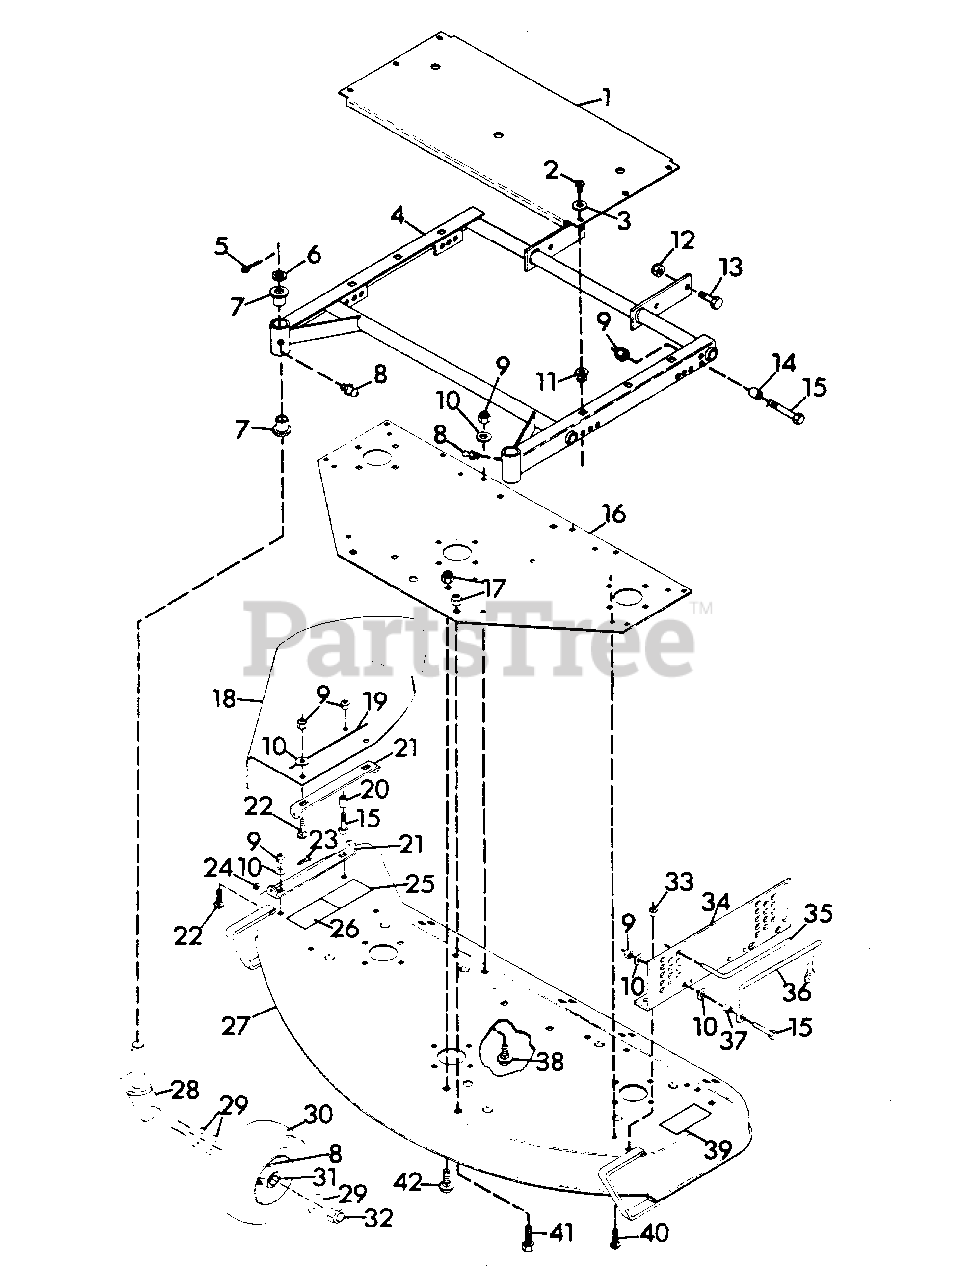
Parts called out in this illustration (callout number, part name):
1	Guard, 50" Mower Belt
2	Screw, Tapping 1/4-20x.625 P/Hd
3	Washer, Flat .281x.625x.065
4	Weldment, Mower Frame
5	Pin, Cotter .187x1.50
6	Race, Bearing Thrust
7	Bushing, Pivot
8	Fitting, Lube 1/4-28
9	Nut, Lock 3/8-16
10	Washer, Flat .406x.812x.065
11	Grommet, Plastic
12	Nut, Lock 5/8-11
13	Bolt, Hex 5/8-11x1.50
14	Bushing .391x.622x.670
15	Bolt, Hex 3/8-16x1.50
16	Assembly, 50" Support Plate
17	Nut, Lock 1/2-13
18	Shield, Safety Ext. 50" Mower
19	Stripe
20	Stop, Chute
21	Bracket, Chute
22	Bolt, 3/8-16x1.00 Rd Hd Sq Nk
23	Bolt, Hex 1/4-20x.875
24	Nut, Lock 1/4-20
25	Decal, Danger Hand
26	Decal, Warning Eye
27	Weldment, 50" Mower Deck
28	Weldment, Caster Fork
29	Washer, Flat .812x1.496x.134
30	Wheel, Gauge
31	Bearing, Gauge Wheel
32	Nut, Lock 3/4-10
33	Nut, Lock 5/16-18
34	Bracket, Mower Side Support L.H.
34	Bracket, Mower Side Support R.H.
35	Pin, Mower Locking
36	Handle
37	Bushing
38	Bolt, Carriage 3/8-16x.75
39	Decal, Danger Foot
40	Bolt, Carriage 5/16-18x1.00
41	Bolt, Hex 1/2-13x1.25
42	Bolt, 1/2-13x1.00 Rd Hd Sq Nk
